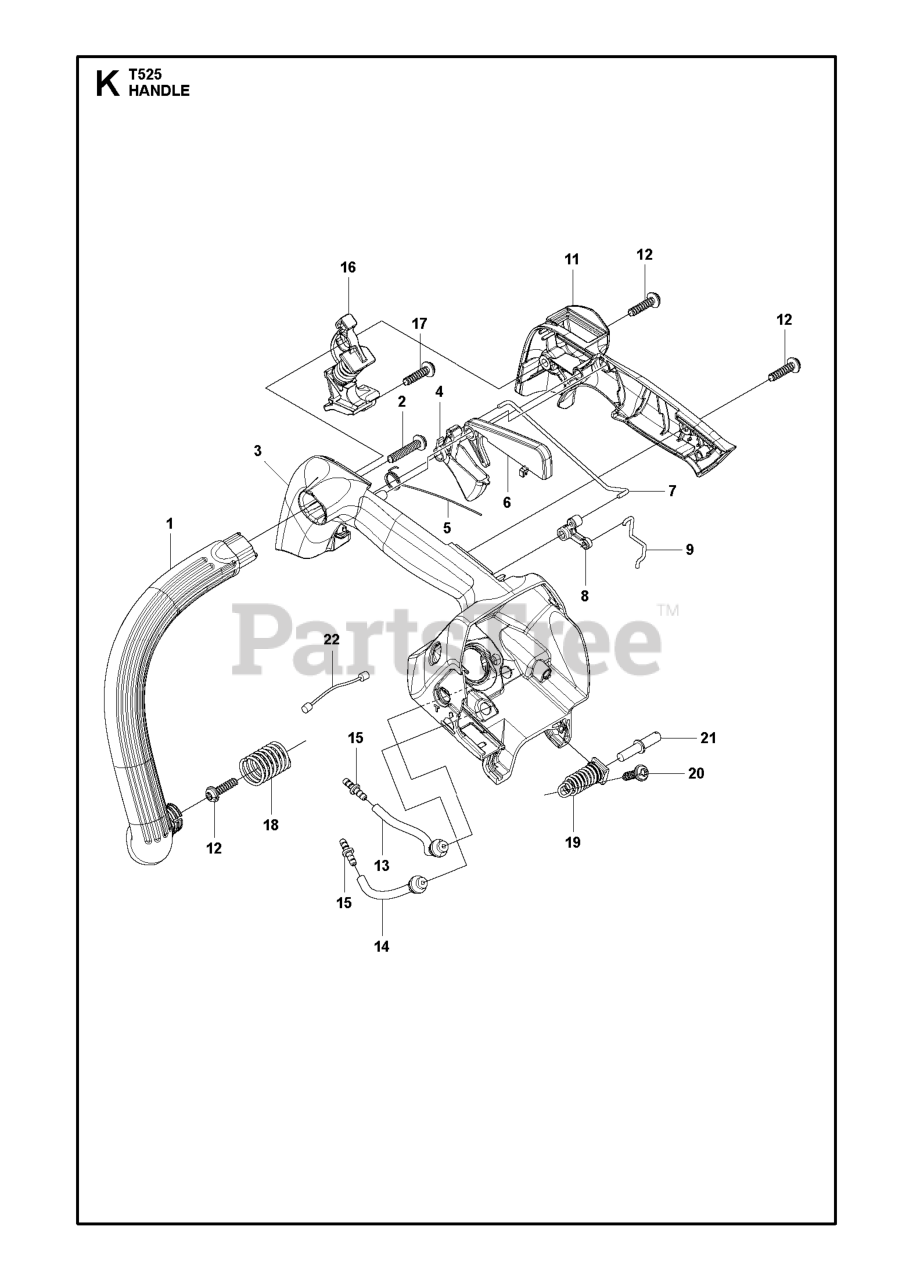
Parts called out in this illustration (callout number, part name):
1	FRONT HANDLE GRAY
3	HANDLE RIGHT ORANGE
4	THROTTLE CONTROL GRAY
6	THROTTLE LOCKOUT GRAY
7	THROTTLE ROD
11	COVER GRIP
11	COVER GRIP ORANGE
13	GROMMET L65
13	GROMMET
14	GROMMET L45
16	ANTIVIBRATION ELEMENT ORANGE
17	SCREW (RPLS 267132210)
19	ANTIVIBRATION ELEMENT
21	BOLT
